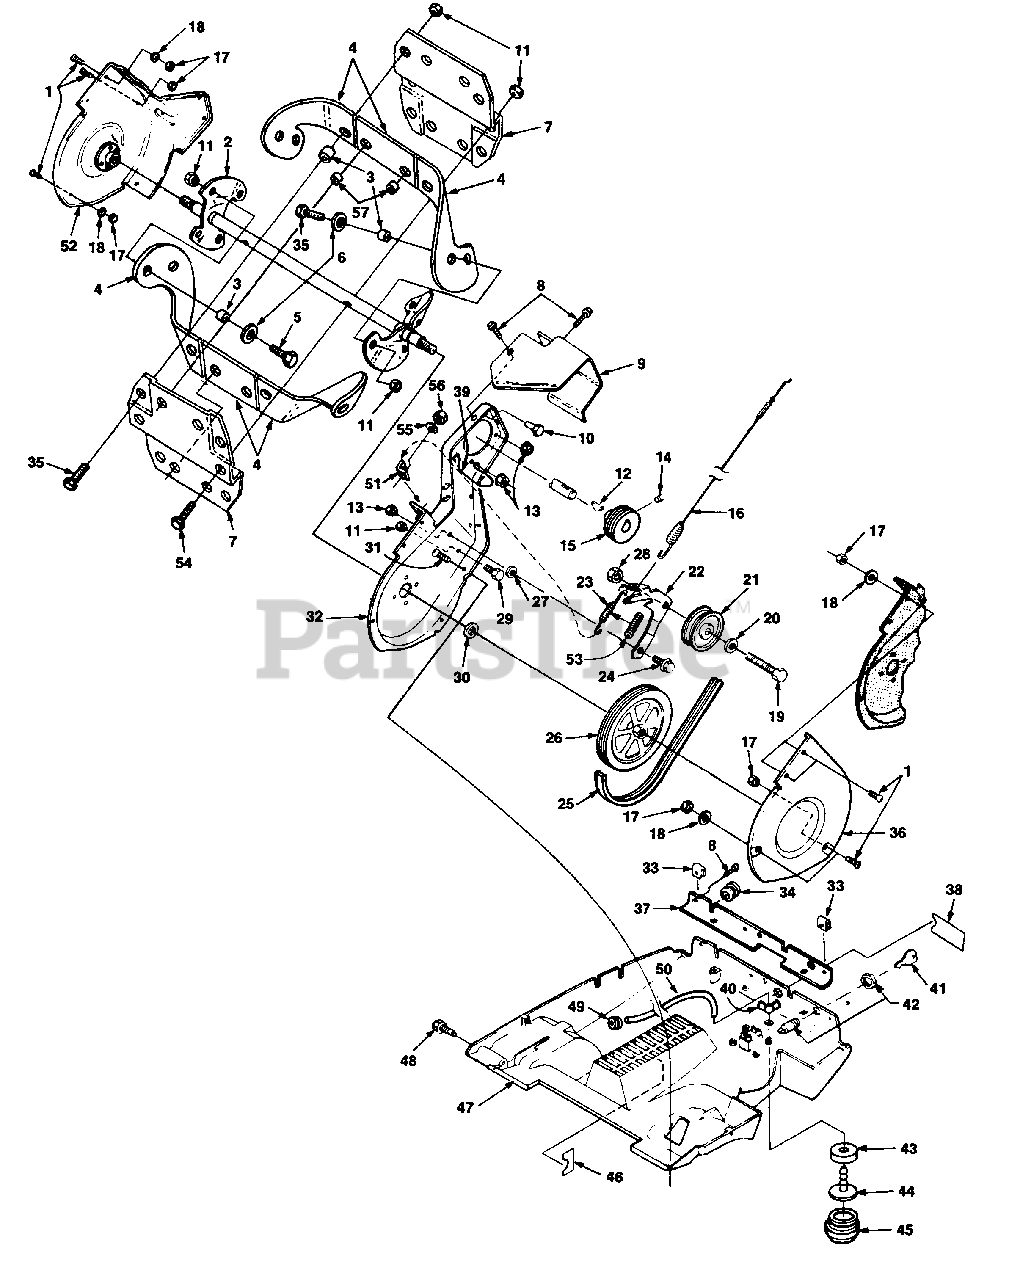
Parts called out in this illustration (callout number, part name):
1	SCREW- Phillips #10-24 x 5/8"
2	SHAFT- Auger
4	BLADE- Auger (set of 2)
5	SCREW- Hex 1/4-20 x 3/4"
6	WASHER- Plain 1/4"
7	CLAMP- Plate
8	SCREW- #10 x 3/4"
9	SHIELD- Belt
10	NUT- 5/16-18
11	NUT- Flange 1/4-20
12	KEY- 5/8 x 5/32"
13	NUT- Flange 5/16-18
14	SCREW- Set 1/4-20 x 3/8"
15	PULLEY- Drive
16	CABLE & SPRING
17	NUT-#10-24
18	WASHER- Retaining
19	SCREW- Hex hd. 3/8-16 x 1 1/2"
20	WASHER- Flat 3/8"
22	ARM- Idler
23	SPRING- Extension
25	BELT- Drive
26	PULLEY- Driven
28	NUT- Hex 3/8-16
29	SCREW- 1/4-20 x 5/8"
31	SCREW- Plastite 1/4-10 x 5/8" Rd. Hd.
32	FRAME- Left side
33	NUT- Speed #10
34	GROMMET- Metal
35	SCREW- Hex 1/4-20 x 7/8"
36	GUARD- Belt
37	BRACKET- Control panel
38	DECAL- Electric start
39	GUIDE- Belt
40	NUT- Wing 1/4-20
41	KEY- Ignition (set of 2)
42	SWITCH- Ignition
43	CUP- Fuel primer
44	FITTING- Fuel primer
45	BULB- Fuel primer
46	DECAL- Fuel valve
47	COWLING- Lower
48	SCREW- 1/4-20 x 5/8"
50	TUBE- Rubber
51	CLIP- Spring
52	FRAME- Right side
53	COVER- Spring
54	SCREW- Hex hd. 1/4-20 x 1 1/4"
55	WASHER- Lock 1/4"
56	NUT- Hex 1/4-20
